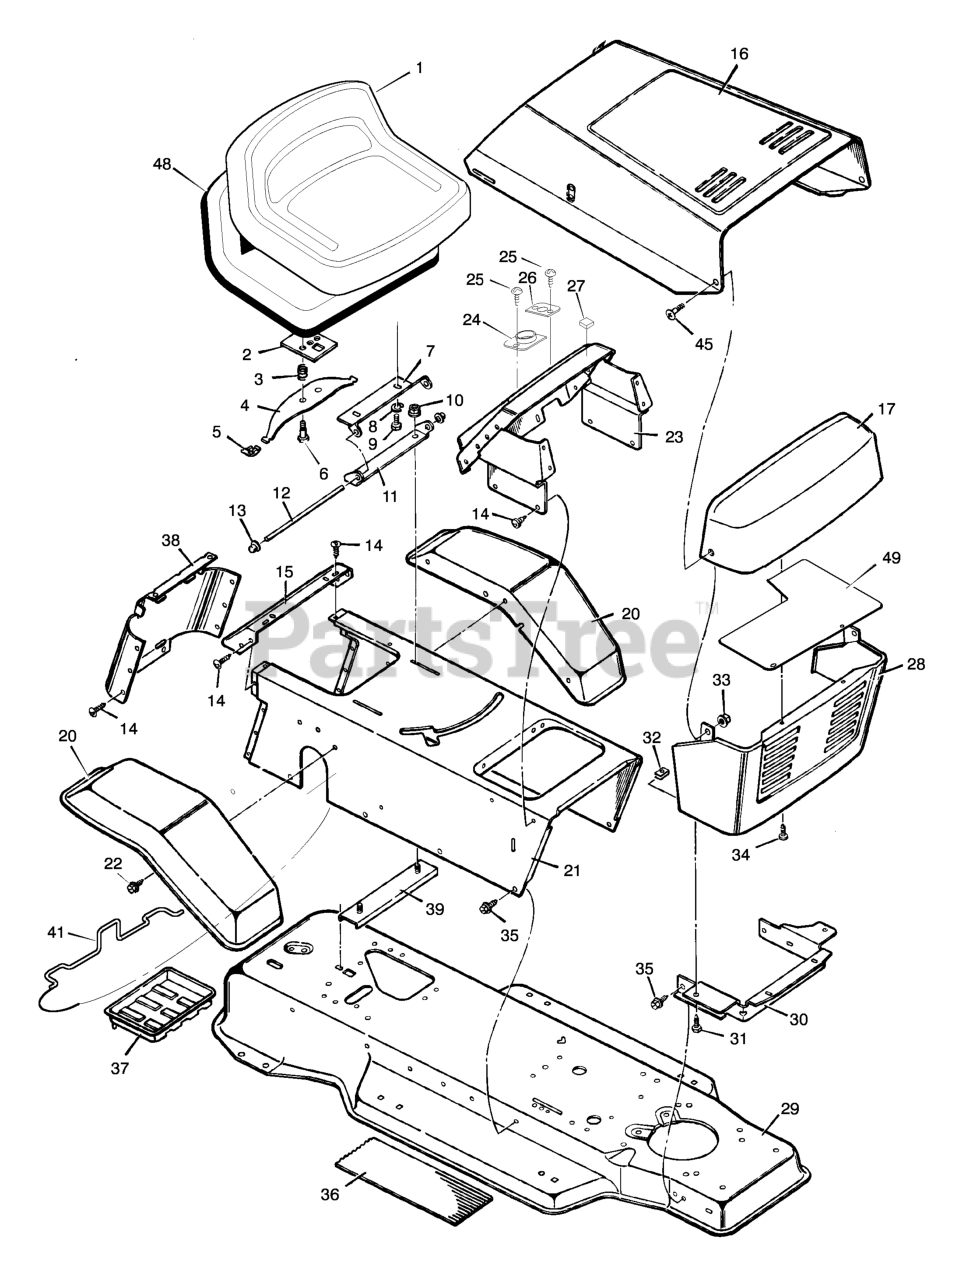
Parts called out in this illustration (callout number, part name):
2	Plate Assembly, Switch
3	Spring, Compression
4	Spring, Seat
5	Glide, Spring
6	Bolt, Shoulder
7	Support, Seat
8	Lockwasher
9	Bolt, Hex
10	Locknut, Flange
11	Bracket, Pivot
12	Rod, Pivot
13	Cap, Push On
14	Screw, Tap
15	Fender, Apron
17	Grille, Upper
21	Console Assembly
23	Dash Panel
24	Bearing, Steering
26	Bearing
27	Bumper
28	Grill, Lower
29	Frame Assembly
30	Support, Grill
33	Locknut, Flange
34	Fastener, Plastic
37	Tray, Battery
38	Cap, Console
39	Channel Assembly
41	Clamp, Battery
45	Bolt, Shoulder
48	Pan, Seat (with foam)
49	Shield, Heat
